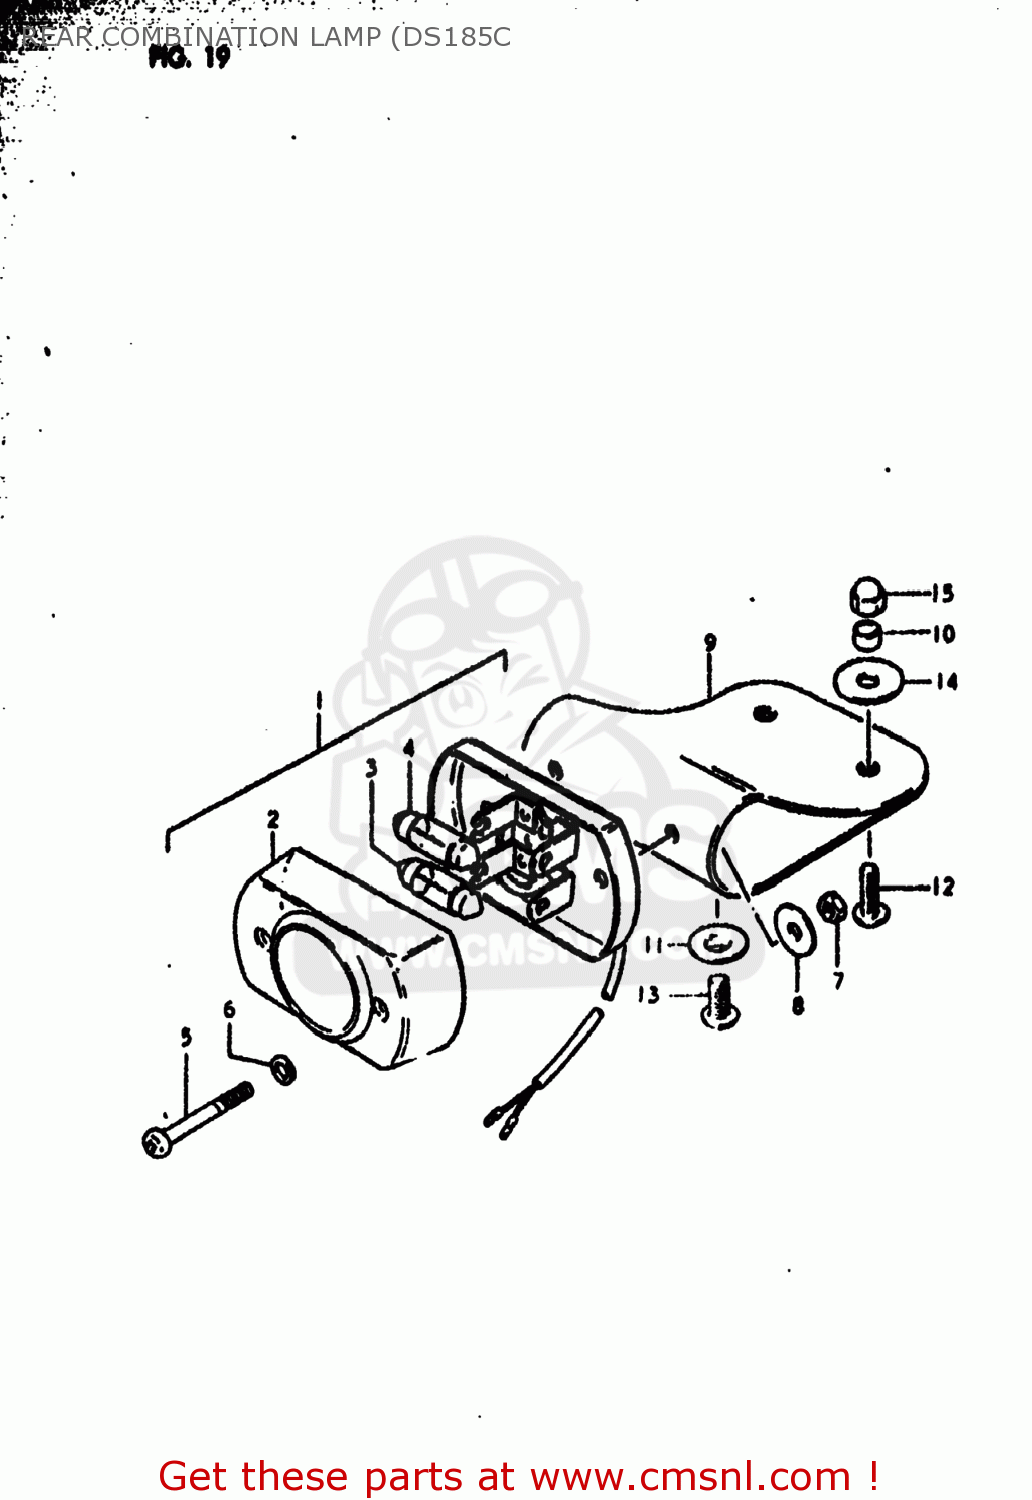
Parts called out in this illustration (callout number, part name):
1	LAMP ASSEMBLY,REAR COMBINATION
2	LENS,REAR COMBINATION LAMP
3	BULB
4	BULB 6V 8W
5	SCREW,REAR COMBINATION LAMP LENS
6	WASHER,REAR COMBINATION LAMP
7	NUT
8	WASHER(5.2X16X1)
9	CUSHION,REAR COMBINATION LAMP
10	SPACER(6.2X8.3X5.7)
11	WASHER
12	SCREW
13	SCREW 6X12
14	WASHER (6.5X20X1.2)
15	NUT
